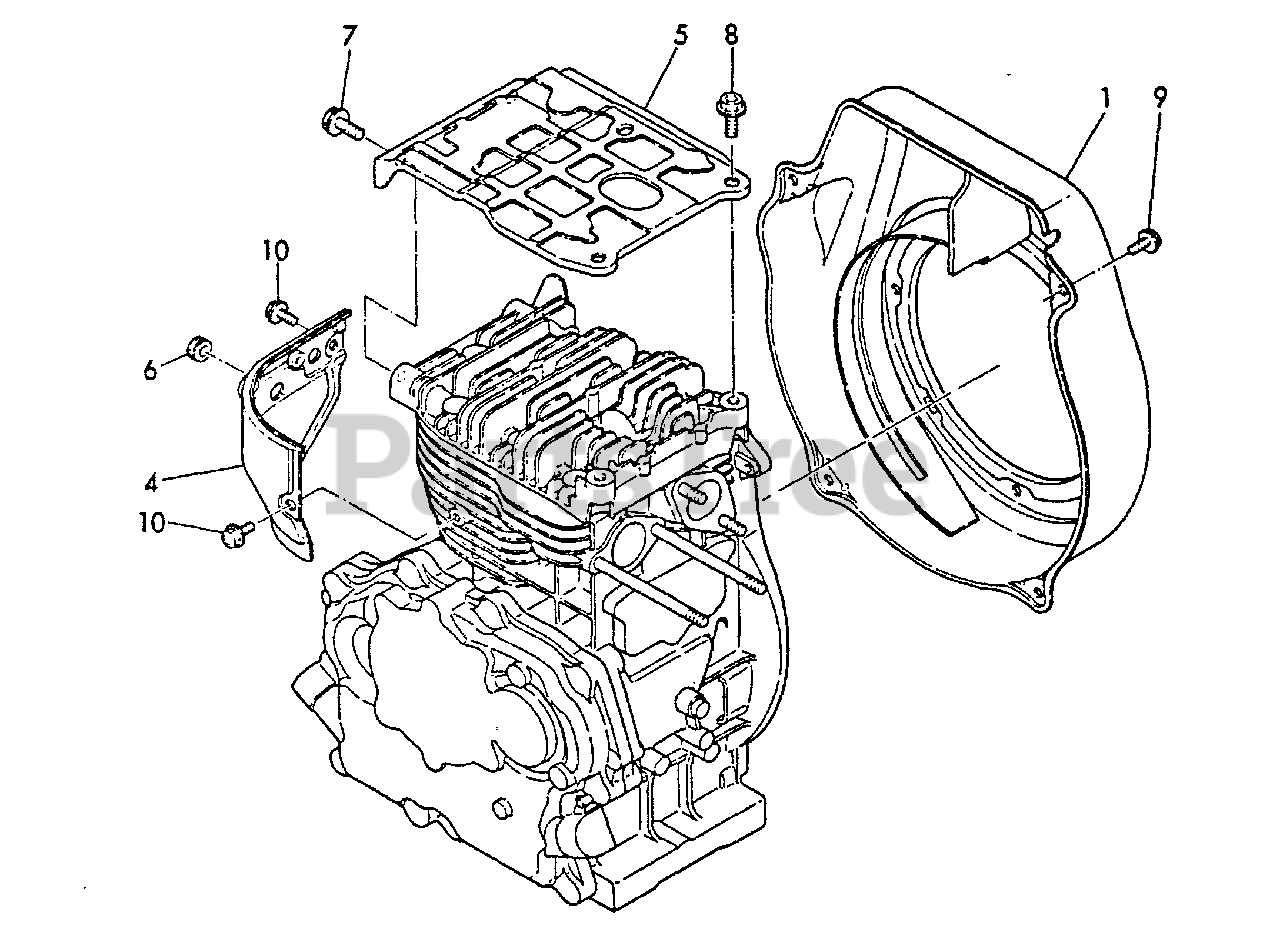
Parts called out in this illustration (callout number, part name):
1	COVER, FAN
4	SHIELD, CYLINDER
5	COVER, HEAD
6	GROMMET
7	BOLT - 8×14 -- PLATED
8	BOLT - 8×20 -- PLATED
9	BOLT - 6×14
10	BOLT - 6×8 -- PLATED
